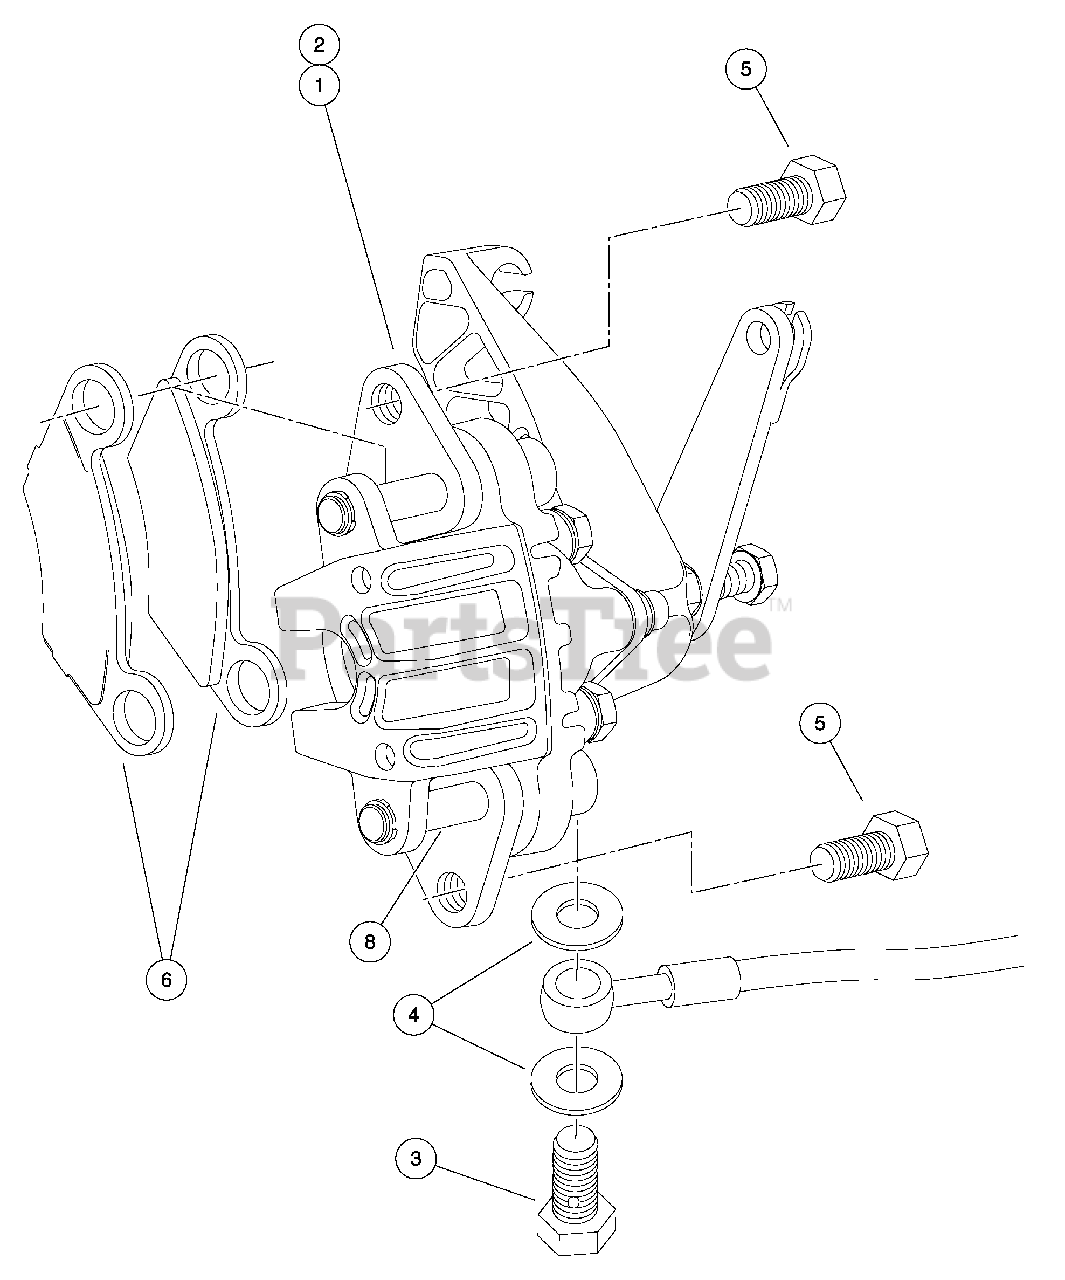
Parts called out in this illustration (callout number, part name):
1	Caliper, Brake, Hydro-Mechanical, LH
2	Caliper, Brake, Hydro-Mechanical, RH
3	Bolt, Banjo, M10x1x19
4	Washer, Copper, M10 Crush
5	Bolt Flange Head, 3/8-24x.750 with Loctite
6	Service Kit, Brake Pad
7	Spring, Brake Caliper Return
8	Pin, Slide, 7/16
